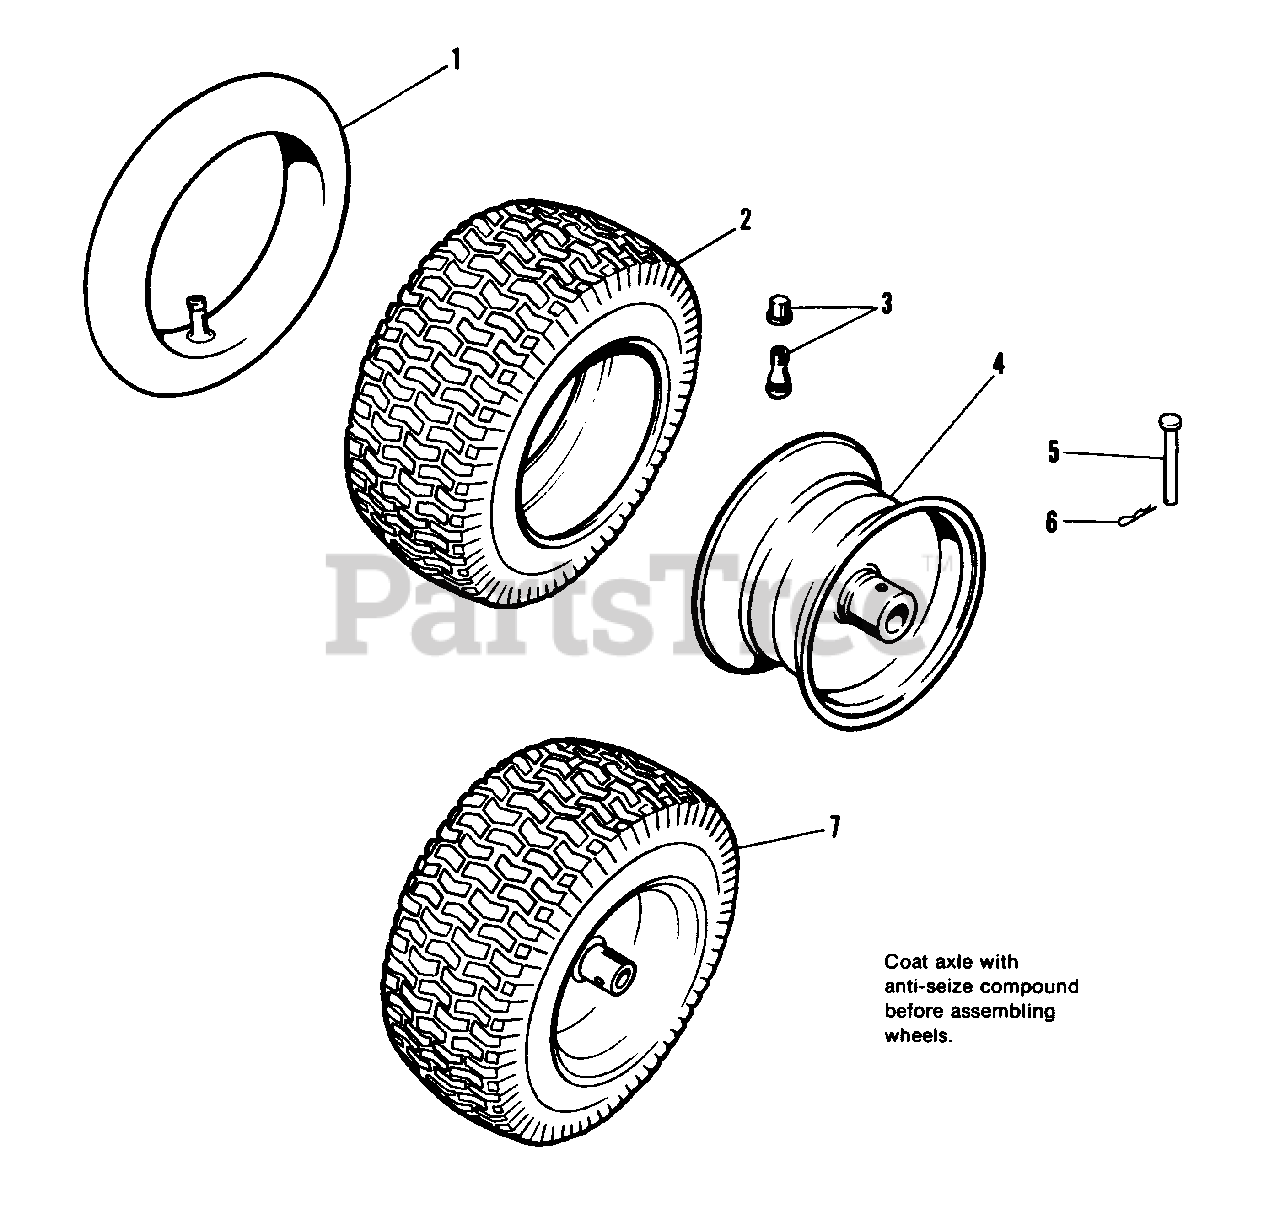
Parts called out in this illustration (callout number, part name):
1	TUBE (Service Only) 4.80/4.00-8
2	TIRE, (4.80/4.00-8)
3	VALVE STEM & CAP
4	WHEEL & HUB ASSY.
5	PIN
6	CLIP, Hair Pin
7	WHEEL & TIRE ASSY.
